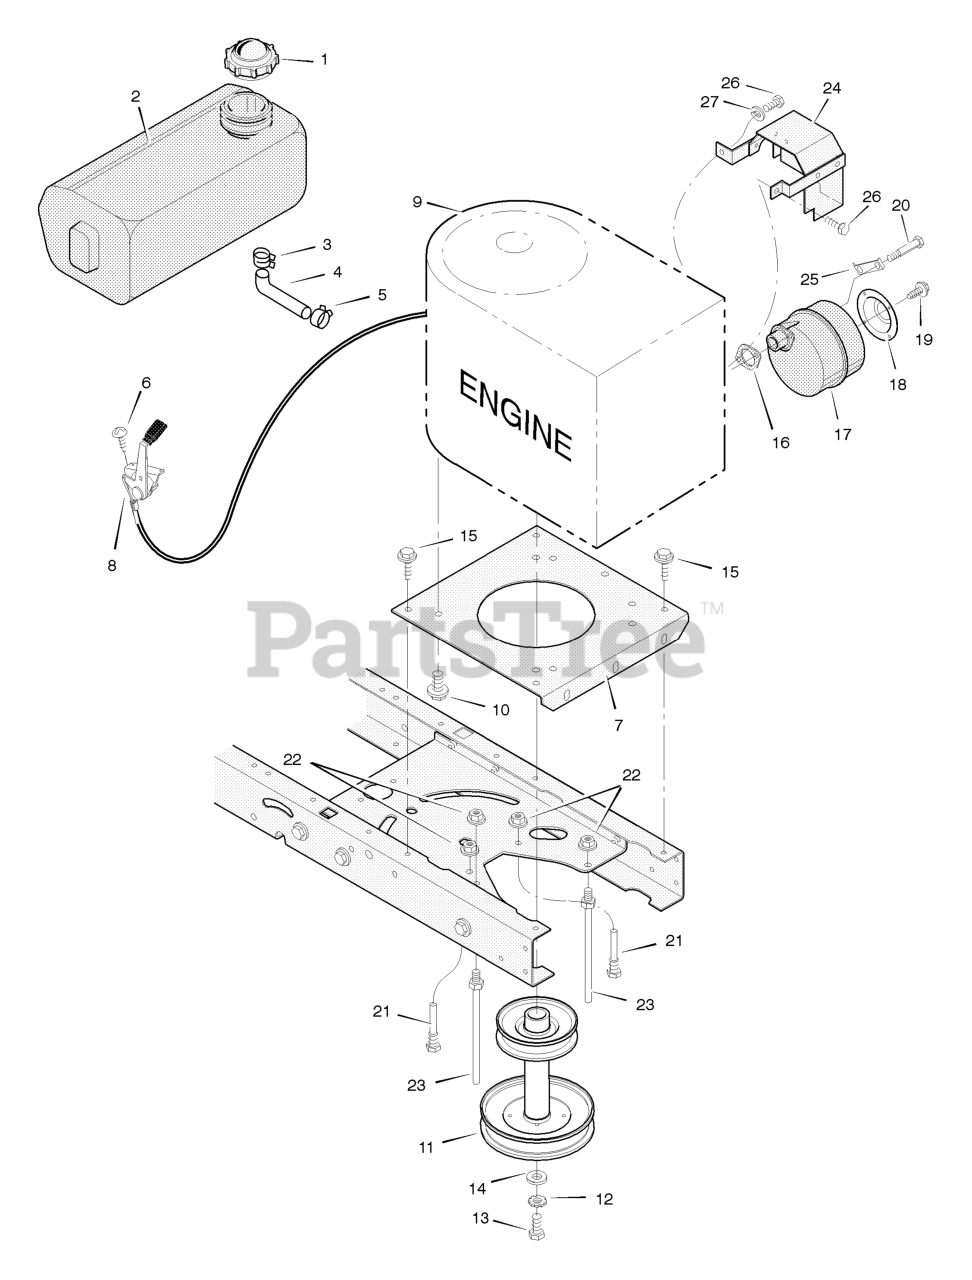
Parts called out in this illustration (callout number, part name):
1	Fuel Cap
2	Fuel Tank
3	Hose Clamp
4	Fuel Line (Must cut to length)
5	Hose Clamp
7	Plate, Engine
8	Throttle Control
9	Engine, Briggs & Stratton *
10	Bolt, Engine Mount
11	STACK PULLEY ASSEMBLY
12	Lockwasher
13	Bolt, Hex
16	GASKET, Exhaust
17	Muffler
18	Deflector, Muffler
20	Bolt, Hex
21	Guide, Belt
22	Nut, Flange
23	Guide, Belt
24	Shield, Heat
25	Lock, Screw
